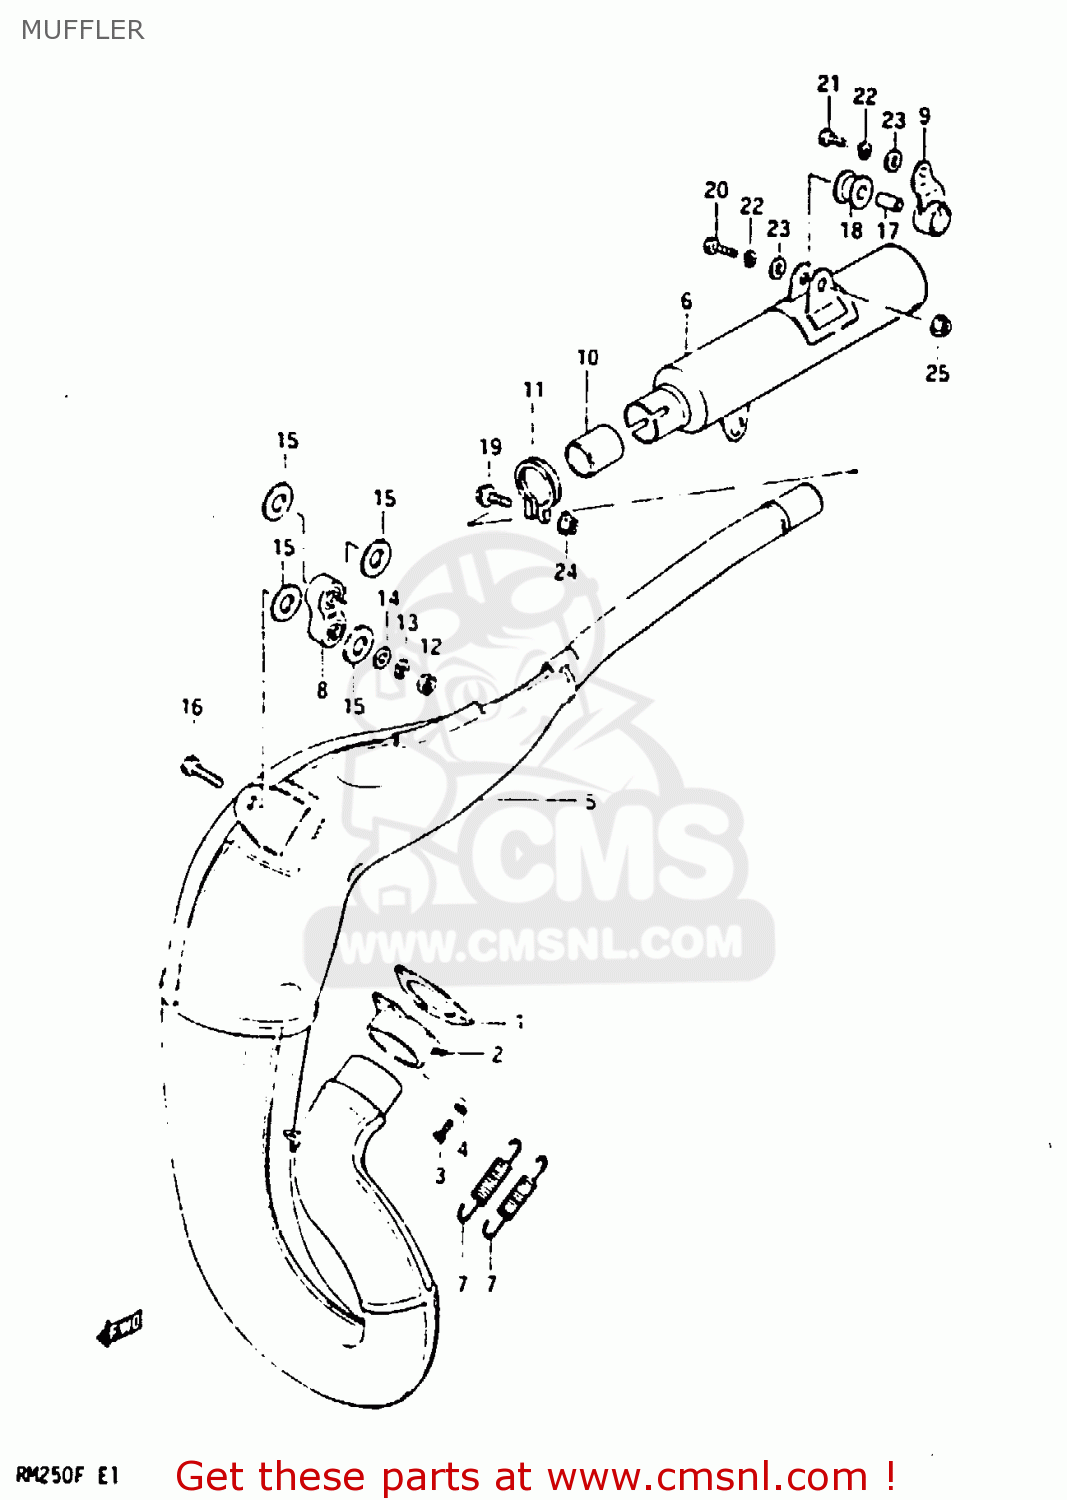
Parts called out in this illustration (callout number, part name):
1	GASKET,EXHAUST PIPE (MCA)
2	FLANGE,EXHAUST PIPE
3	SCREW
4	LOCK WASHER
5	MUFFLER, 1ST
6	MUFFLER, 2ND
7	SPRING
8	DAMPER,MUFFLER
9	DAMPER,MUFFLER SUPPORT
10	CONNECTOR,MUFFLER
11	CLAMP,MUFFLER 2ND
12	NUT 8MM
13	LOCK WASHER
14	WASHER
15	WASHER(13X28X1.6)
16	BOLT(8X32)
17	SPACER (8.6X12X17.5)
18	CUSHION
19	BOLT
20	BOLT
21	BOLT
22	LOCK WASHER
23	WASHER
24	NUT 6MM
25	NUT
